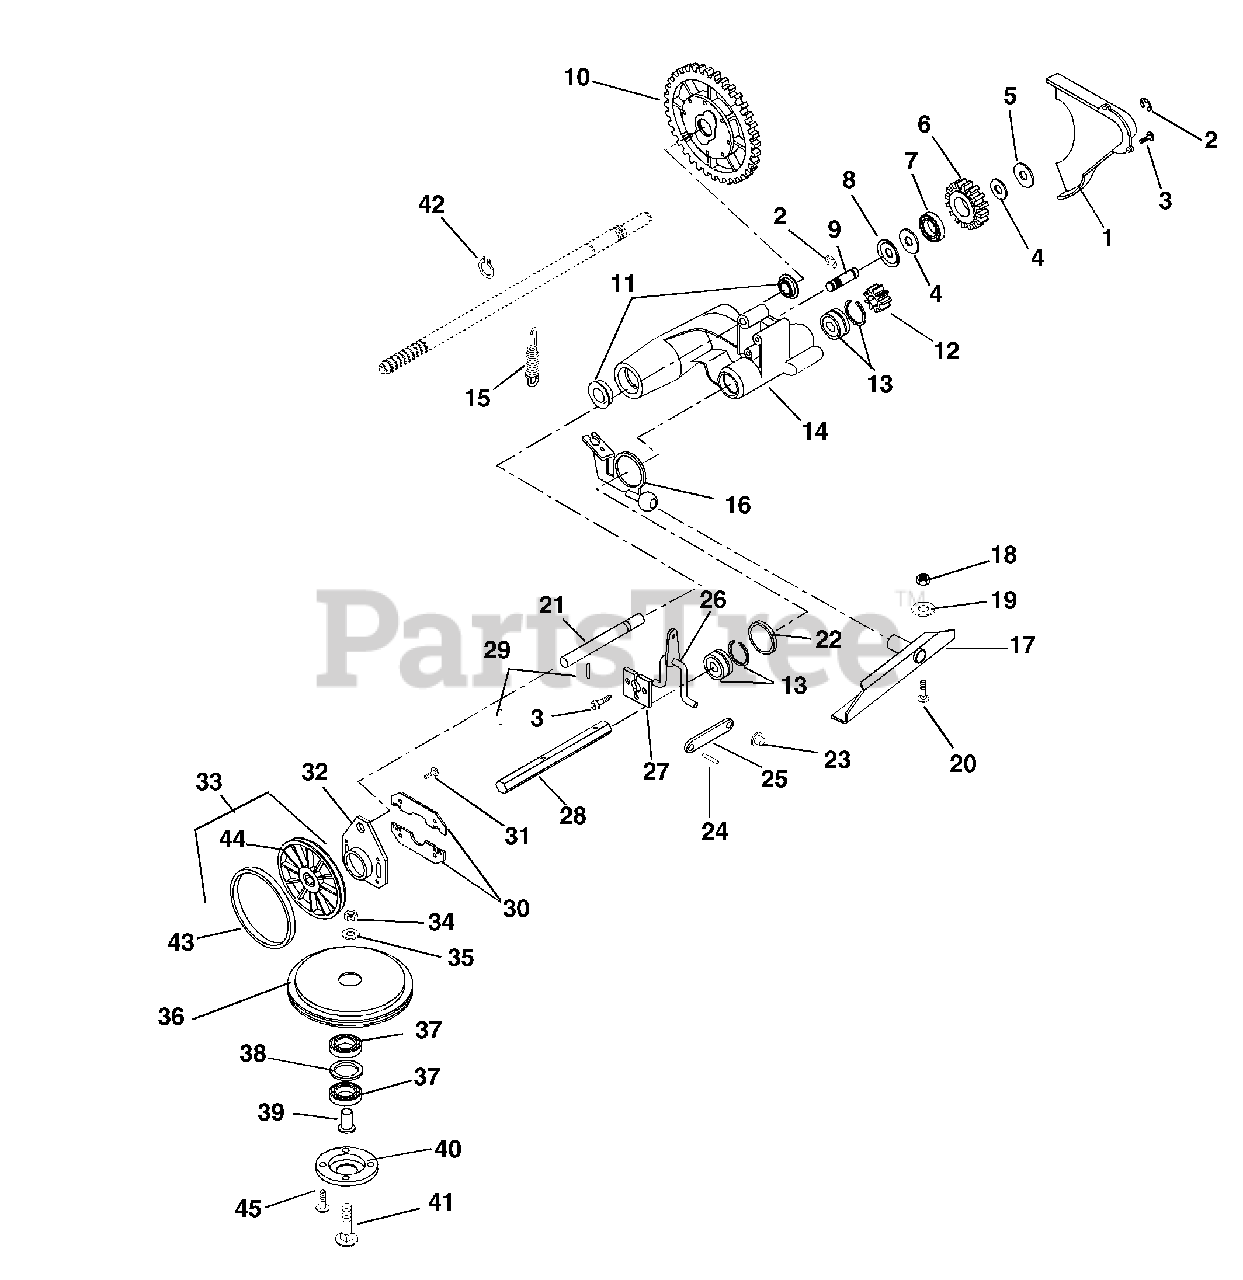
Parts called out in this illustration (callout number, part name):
1	COVER, GEAR
2	RG-RTNG-EXT .438X.035
3	@SCR-TAP 12-24X.50 HWH TR YWZC
4	WSHR-FL-STL .52X.827X.062 YWZC
5	WSHR-FL-STL.531X1.00X.063 YWZC
6	IDLER GEAR
7	BRG-BALL .500X1.38X.437
8	RETAINER
9	IDLER SHAFT
10	DIFFERENTIAL ASSEMBLY
11	BRG-BALL .625X1.383X.50
13	BRG-BALL .562X1.375X.437
14	DRIVE MOUNT
15	SG-TENS .051X.60X2.25 WLD 7.0
16	DRIVE ACTUATOR WELDMENT
17	PIVOT, CHANNEL WELDMENT
18	@NUT-LK-CTR .31-18 YWZC
19	@WSHR-FL-STL.344X.688X.065YWZC
20	@BLT-RHDSSQNK .31-18X.62 G5YZ
21	ROD - GUIDE
22	WSHR-FL-STL 1.390X2.00X.020 PL
23	PUSH NUT, .25
24	PIN-ROLL .125X.50
25	SHIFT LINK
26	SHIFT ARM WELDMENT
27	RETAINER PLATE
28	HEX SHAFT
29	PIN-ROLL .188X.88
30	THRUST PLATE
31	@SCR-TAP 10-24X.375 HWH YZ TR
32	GUIDE PLATE
33	FRICTION WHEEL ASSEMBLY
34	@NUT-LK-CTR .31-18 YWZC
35	WSHR-FL-STL .328X.87X.179 YWZC
36	FRICTION SHEAVE
37	BRG-BALL .625X1.375X.43
38	WSHR-FL-STL 1.062X1.344X.032PL
39	SPINDLE - BEARING
40	RETAINER - BEARING
41	@BLT-RDHDSQNK .31-18X1.75 G5YZ
42	RG-RTNG-EXT .579X.035
43	RING, FRICTION
44	FRICTION WHEEL HUB
45	@SCR-TAP 12-24X.50 HWH TR YWZC
